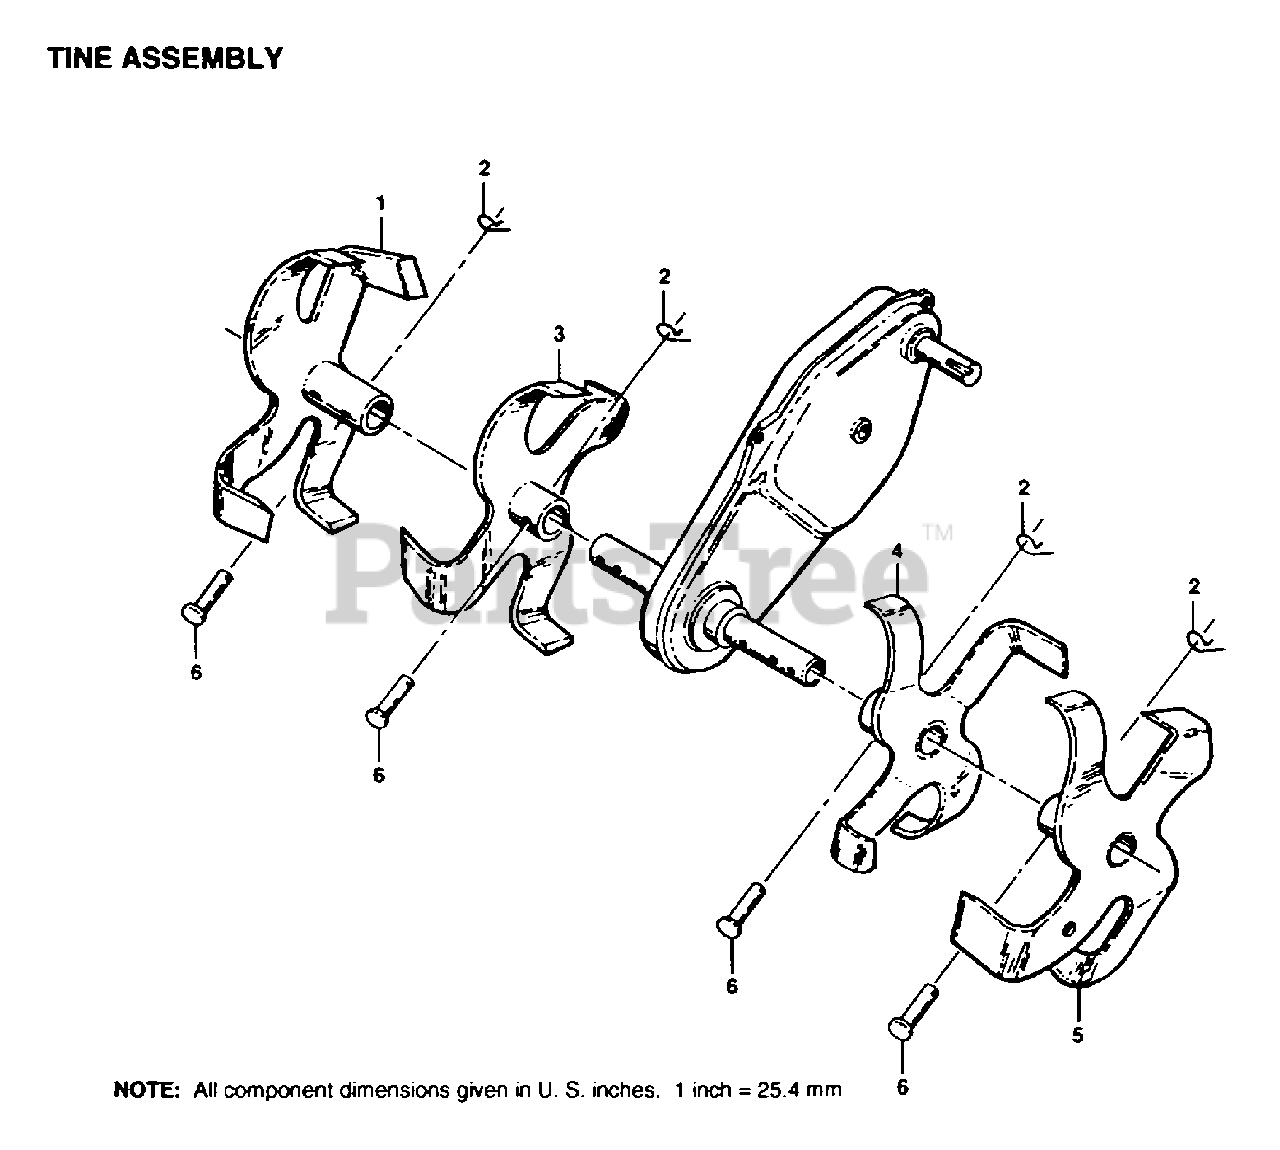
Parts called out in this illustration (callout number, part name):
1	TINE ASSY RH
2	SPRING.RETAINER
3	TINE ASSY RH
4	TINE INN LH TI
5	TINE ASS'Y LH
6	DRILLED RIVET RT
